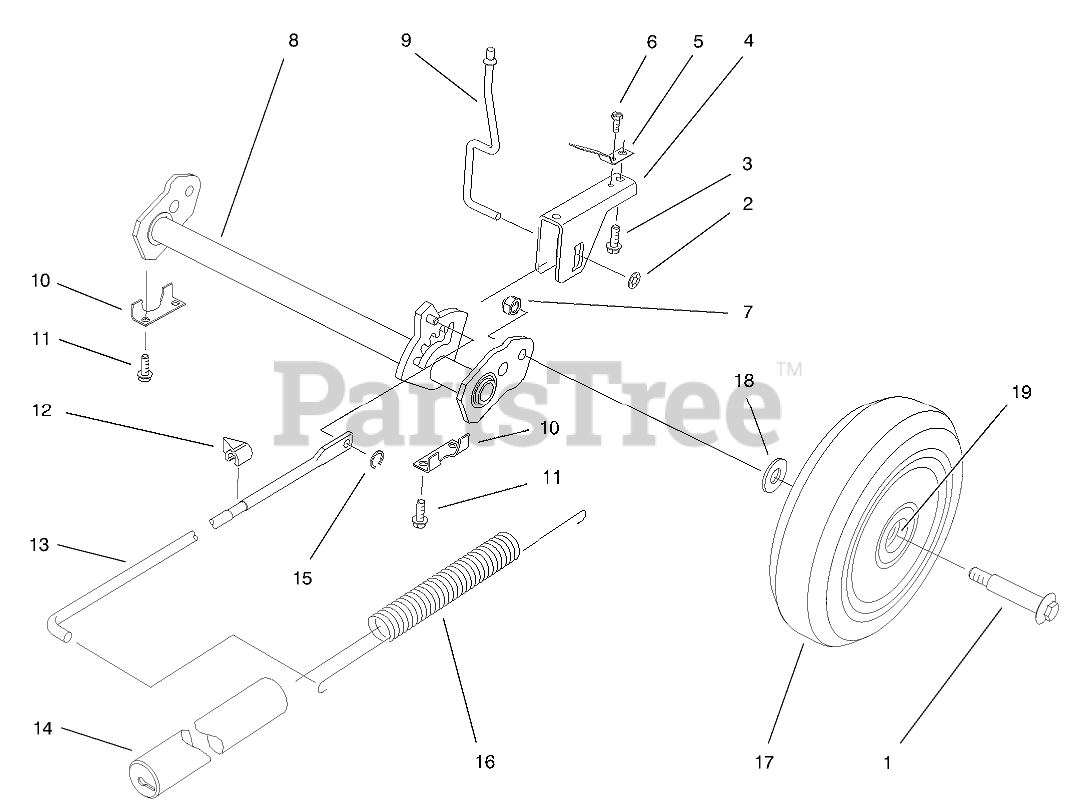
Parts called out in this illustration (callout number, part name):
1	BOLT-WHEEL
2	PUSHNUT
3	SCREW
4	SADDLE - HOC
5	SPRING - TRIGGER RET
6	SCREW 8 - 32 X 250
7	NUT-HEX
8	PIVOT ARM REAR WA
9	TRIGGER ROD
10	REAR SECURING PLATE
11	SCREW-HWH
12	INDICATOR-HEIGHT OF CUT
13	LINK ROD
14	COVER-SPRING
15	GRIP RING
16	SPRING-COUNTERBALANCE
17	Rear Wheel & Tire Assembly (Incl. Ref. # 19)
18	WASHER
19	BUSHING
